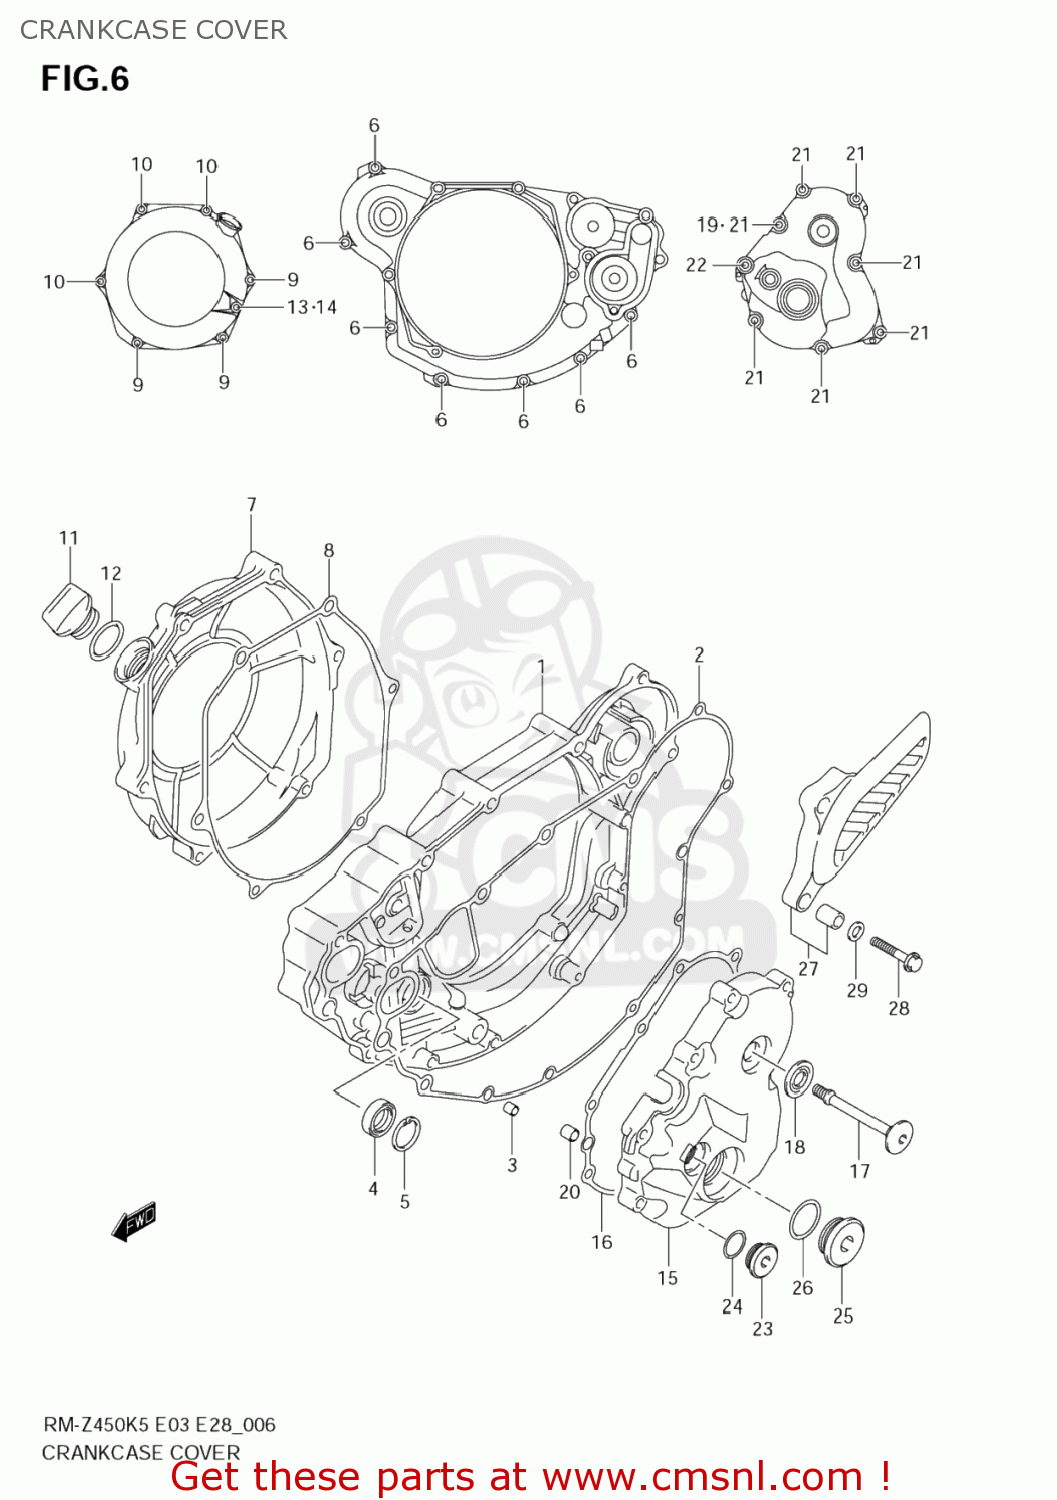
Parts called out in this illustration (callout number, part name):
1	COVER,CLUTCH
2	GASKET,CLUTCH COVER (NAS)
3	PIN
4	SEAL,OIL(12X22X6)
5	CIRCLIP
6	BOLT(6X25)
7	COVER,CLUTCH OUTER
8	GASKET,CLUTCH COVER OUTER (NAS)
9	BOLT(6X30)
10	BOLT(6X70)
11	PLUG
12	O RING(D:3.1,ID:16.8)
13	BOLT
14	GASKET(6.2X11X1).2 (NAS)
15	COVER,MAGNETO
16	GASKET,MAGNETO COVER (NAS)
17	BOLT,MAGNETO COVER
18	WASHER(10.6X25.5X2.3)
19	GASKET(6.2X13X1.2) (NAS)
20	PIN
21	BOLT(6X25)
22	BOLT(6X30)
23	PLUG(12X9)
24	O RING(D:1.9,ID:9.8)
25	PLUG(26X9)
26	O RING(D:3.1,ID:22.7)
27	COVER,ENGINE SPROCKET
28	BOLT(6X30)
29	WASHER
